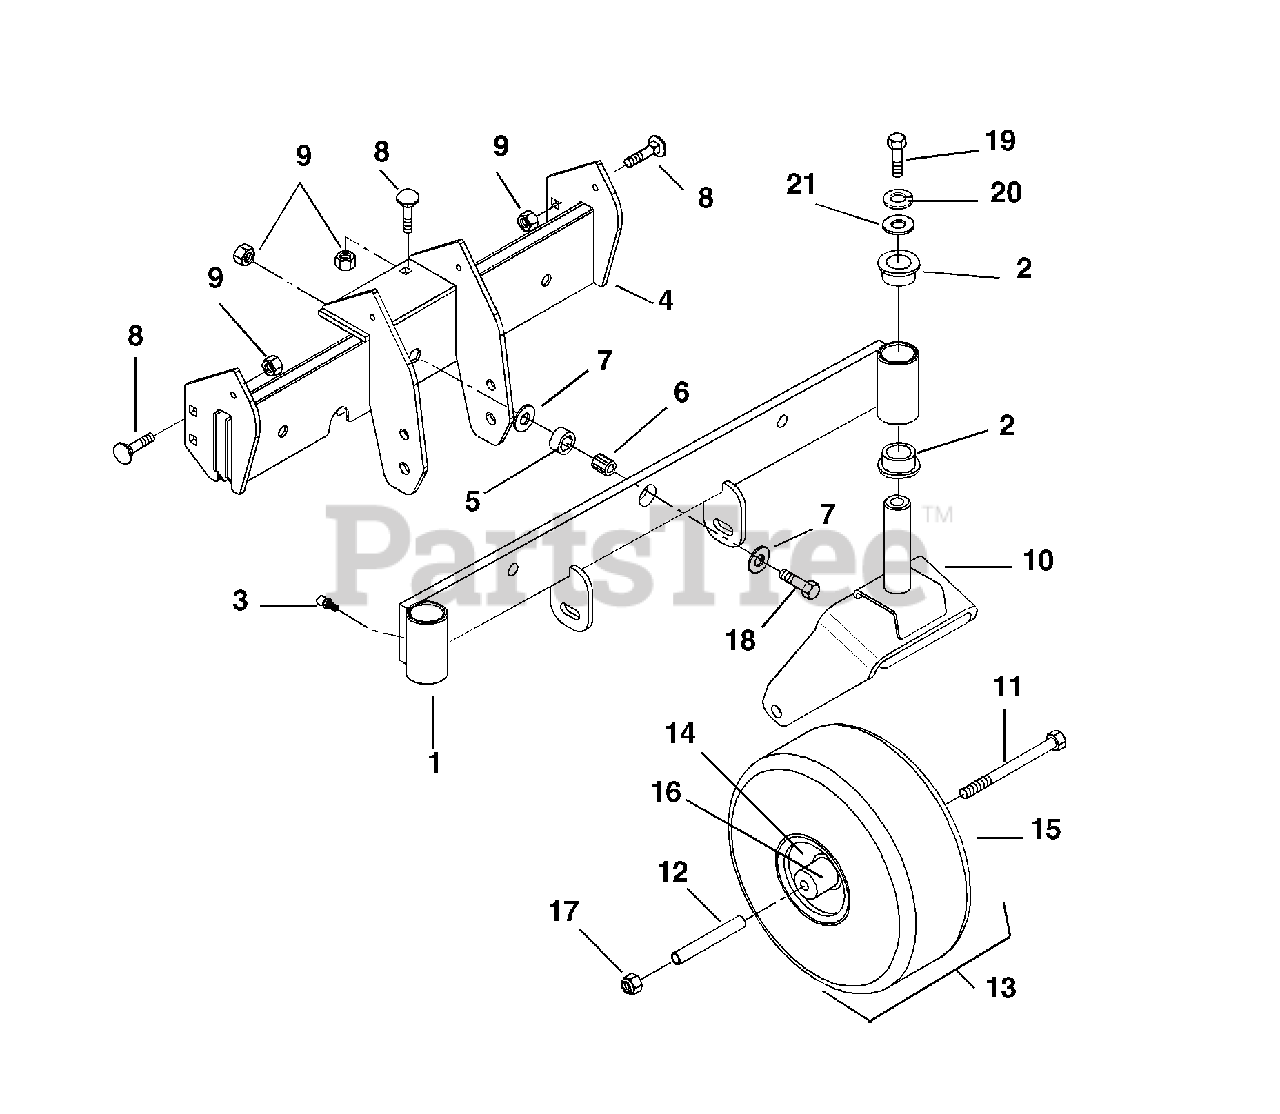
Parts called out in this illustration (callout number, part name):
1	AXLE WELDMENT
2	BSHG-FLG1.020X1.385X.75X1.75NY
3	FTG-LUBE .25-28X.256 YWZC
4	WELDMENT, AXLE FRAME
5	BSHG-SLV .626X1.000X.524 HEX
6	BSHG-SLV .377X.623X.775 HEX
7	WSHR-FL-STL .380X1.50X.125YWZC
8	@BLT-RDHDSQNK .38-16X.75 G5YZ
9	@NUT-LK-CTR .38-16 YWZC
10	FORK - CASTER
11	@BLT-HEX .50-13X6.50 GR5 YWZC
12	BUSH.,CASTER FORK
13	T/WHL 11X4.00-5 RIBBED
14	RIM ASSY 11X4.00-5
15	TIRE RIBBED 11X4.00-5
16	RIM BEARING-11X4.00-5 RIM
17	@NUT-LK-CTR .50-13 YWZC
18	@BLT-HEX .38-16X1.50 GR5 YWZC
19	@BLT-HEX .38-16X1.25 GR5 YWZC
20	@WSHR-LK .38X.094 REG YWZC
21	WSHR-FL-STL .390X1.5X.125 YWZC
